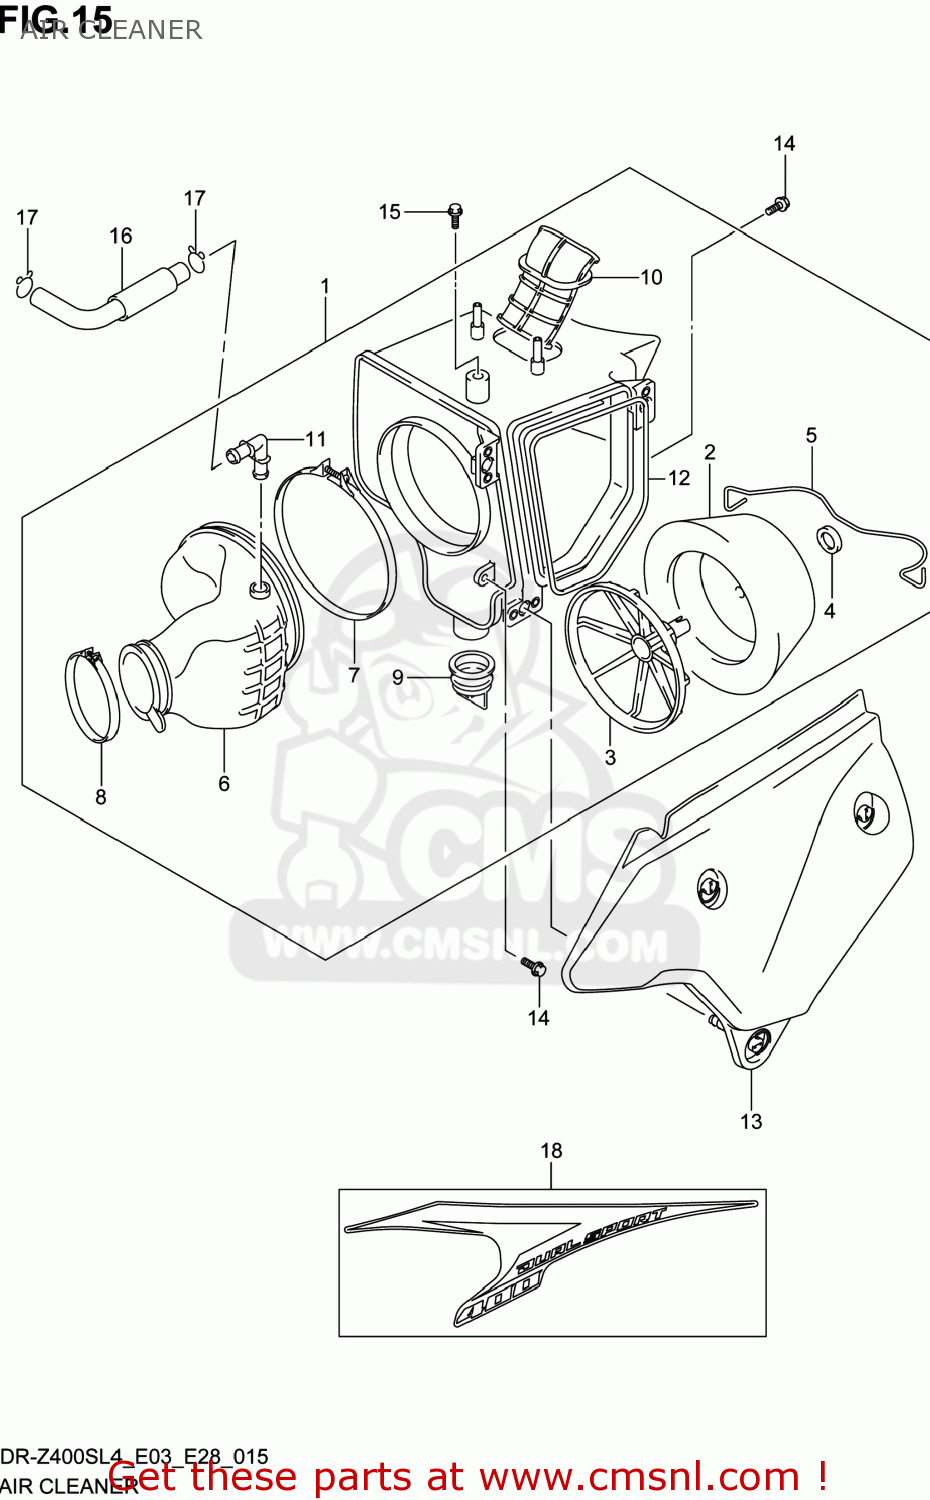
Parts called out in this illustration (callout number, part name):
1	CLEANER,AIR
2	FILTER ASSY
3	HOLDER,FILTER
4	SPACER
5	SPRING
6	TUBE,OUTLET
7	CLAMP
8	CLAMP
9	VALVE
10	TUBE,INLET
11	JOINT
12	GASKET,AIR CLEANER (NAS)
13	CAP COMP,AIR CLEANER
14	BOLT
15	BOLT(6X14.6)
16	TUBE,BREATHER
17	CLIP
18	TAPE,AIR CLNR CAP
